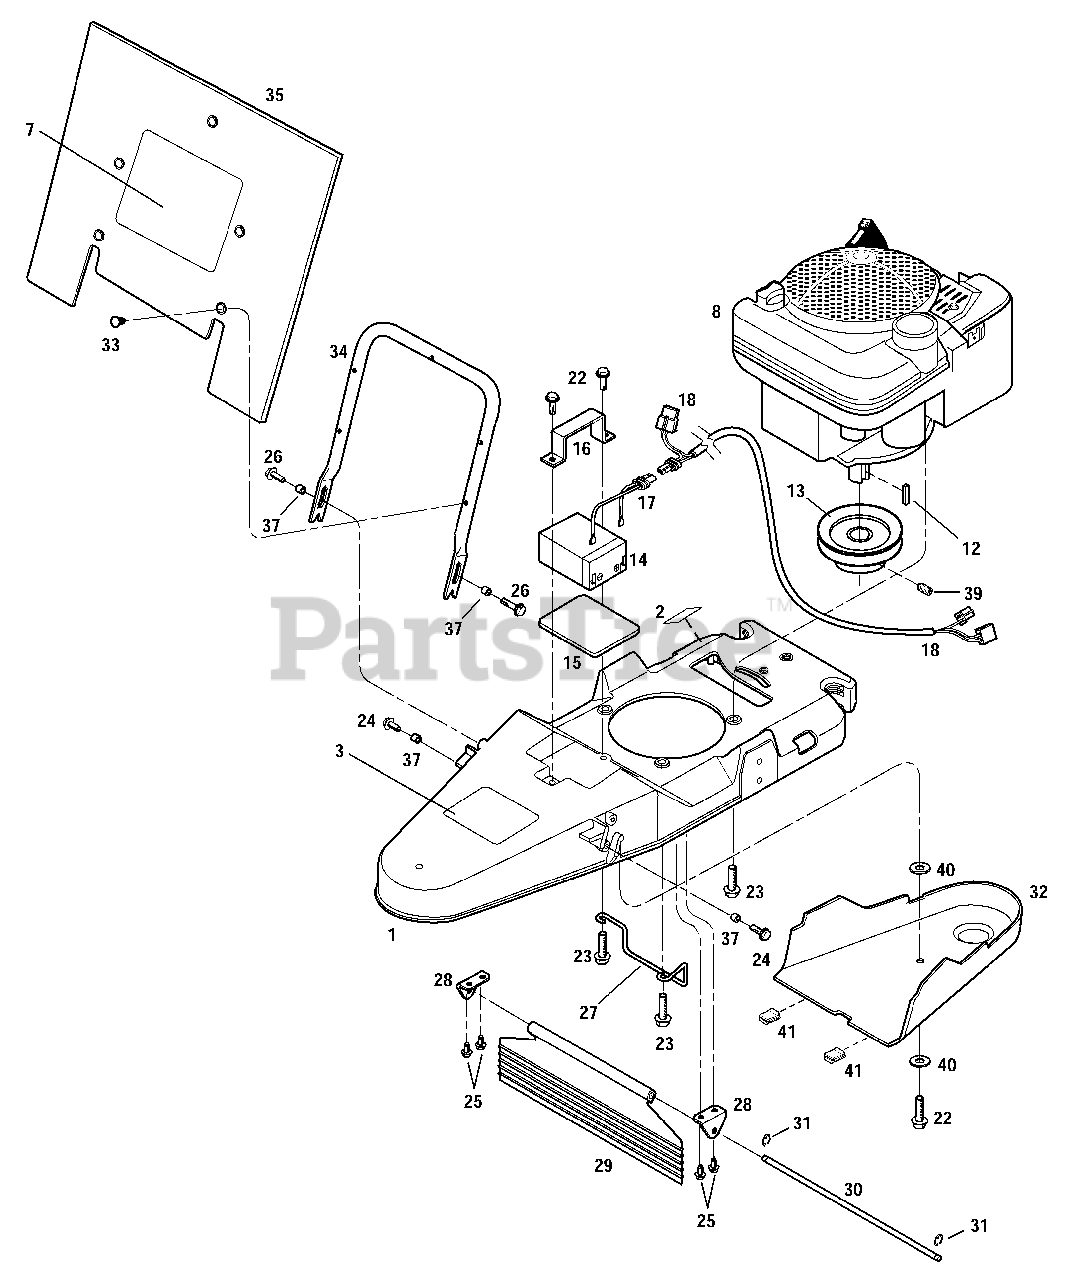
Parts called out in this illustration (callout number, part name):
1	Deck
2	Decal-Hot Surface
3	Decal-Warning/Thrown Objects
7	Decal-Logo
8	Engine - Recoil Start
12	Key, 3/16" x 1" Sq.
13	Pulley, 4" OD
14	Battery
15	Pad - Battery
16	Bracket - Battery
17	Battery Wire Connector
18	Keyswitch Wire Harness
22	Hex Hd. Flange Screw, 5/16-18 x 1
23	Hex Hd. Flange Screw, 3/8-16 x 1-1/2
24	Hex Hd. Flange Screw, 1/4-20 x 3/4
25	Hex Hd. Flange Screw, 1/4-20 x 5/8
26	Hex Hd. Flange Screw, 1/4-20 x 1
27	Belt Guide
28	Flap Bracket
29	Deflector Flap
30	Deflector Flap Rod
31	E-Ring, 5/16"
32	Belt Cover
33	Push-In Fastener
34	Debris Guard Support
35	Debris Guard
37	Spacer
39	Set Screw
40	Washer
41	Clip
